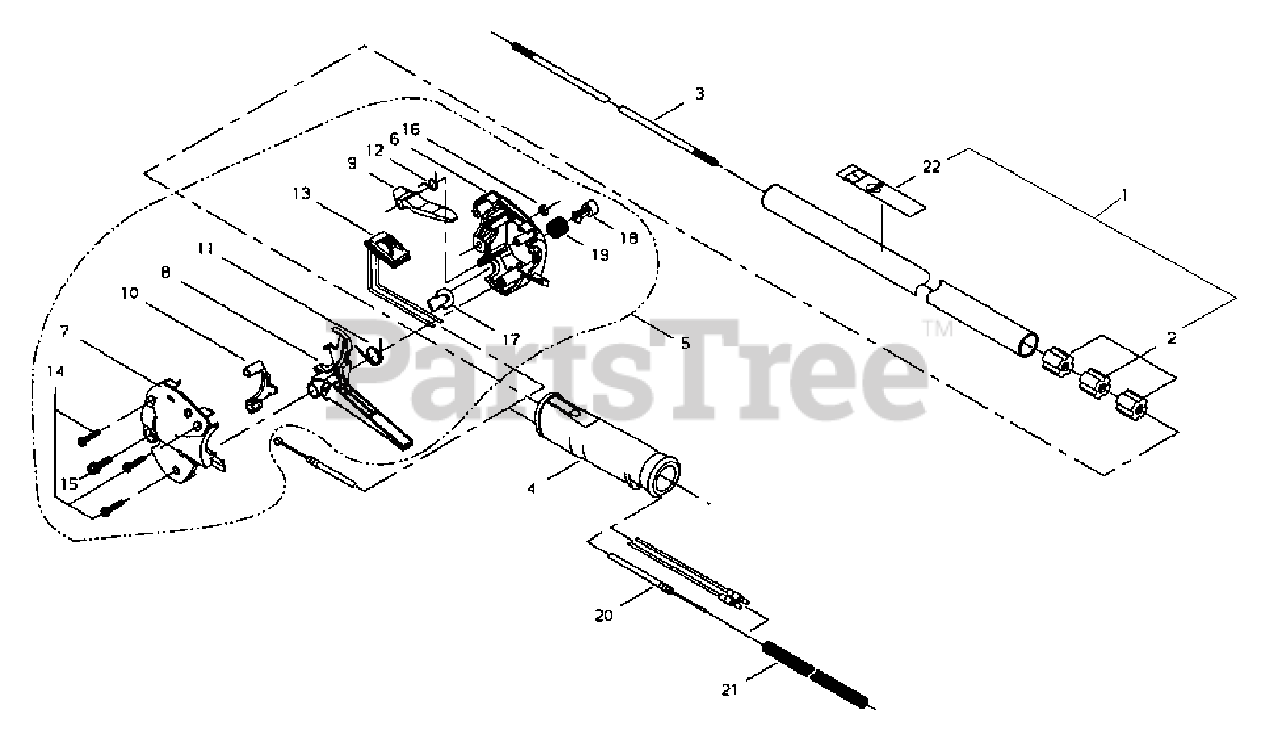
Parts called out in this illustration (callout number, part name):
1	MAIN PIPE ASSY
2	BUSHING
3	PIPE, MAIN
4	GRIP
5	THROTTLE LEVER ASSY
6	HANDLE, CONTROL - RIGHT
7	HANDLE, CONTROL - LEFT
8	TRIGGER, THROTTLE
9	LEVER, TRIGGER LOCKOUT
10	LOCKOUT, THROTTLE
11	SPRING
12	SPRING
13	SWITCH, IGNITION
14	SCREW - 4X20 -- TAPPING
15	SCREW - 5X20
16	NUT - 5
17	PLUG
18	BUTTON, THROTTLE LOCK
19	SPRING
20	CABLE, THROTTLE
21	TUBE
22	LABEL - CAUTION
23	LABEL - CAUTION
